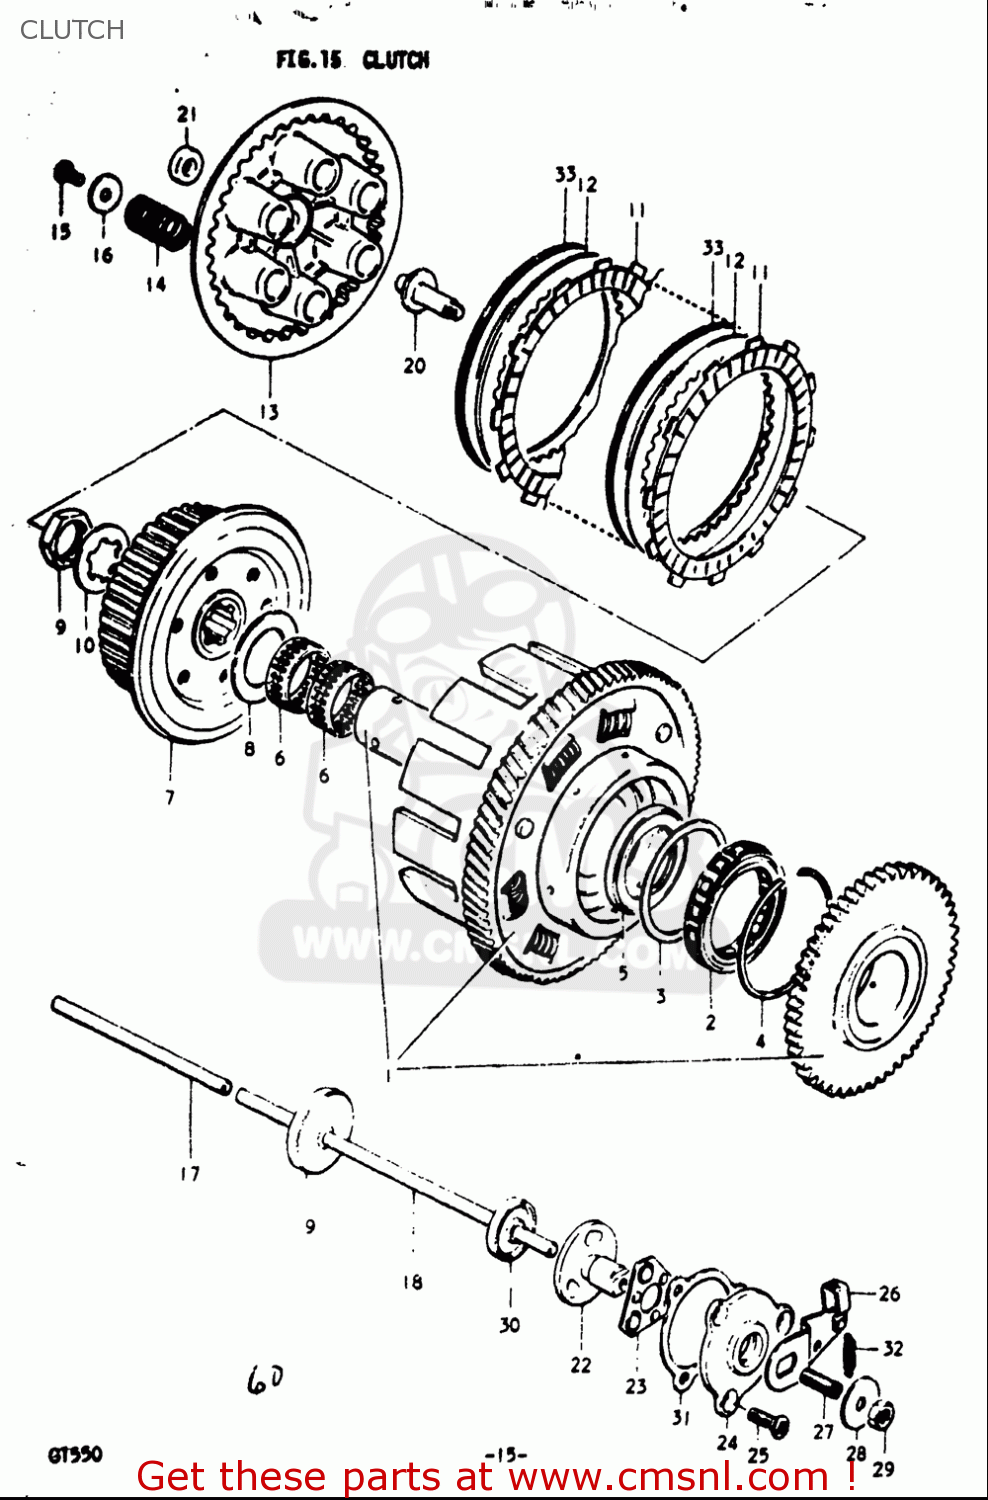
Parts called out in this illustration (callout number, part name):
1	GEAR ASSEMBLY,PRIMARY DRIVE
3	WASHER
5	BEARING
6	ROLLER BEARING (38X43X2
8	THRUST WASHER
9	NUT
10	WASHER,LOCK
11	PLATE,CLUTCH DRIVE (NAS)
12	PLATE,CLUTCH DRIVEN (NAS)
14	SPRING
15	BOLT
16	WASHER(6.5X20X1.6)
18	ROD,CLUTCH PUSH NO.2
19	SEAL,OIL(8X47X7)
21	SEAL,OIL (10X17X5)
22	GUIDE,CLUTCH RELEASE,OUTER
23	BALL,CLUTCH RELEASE
25	SCREW
27	SCREW
28	WASHER(8.5X26X1.2)
29	NUT
30	SEAL,OIL(8X32X6.5)
31	GASKET,BALL GUIDE (NAS)
32	SPRING
33	V RING
